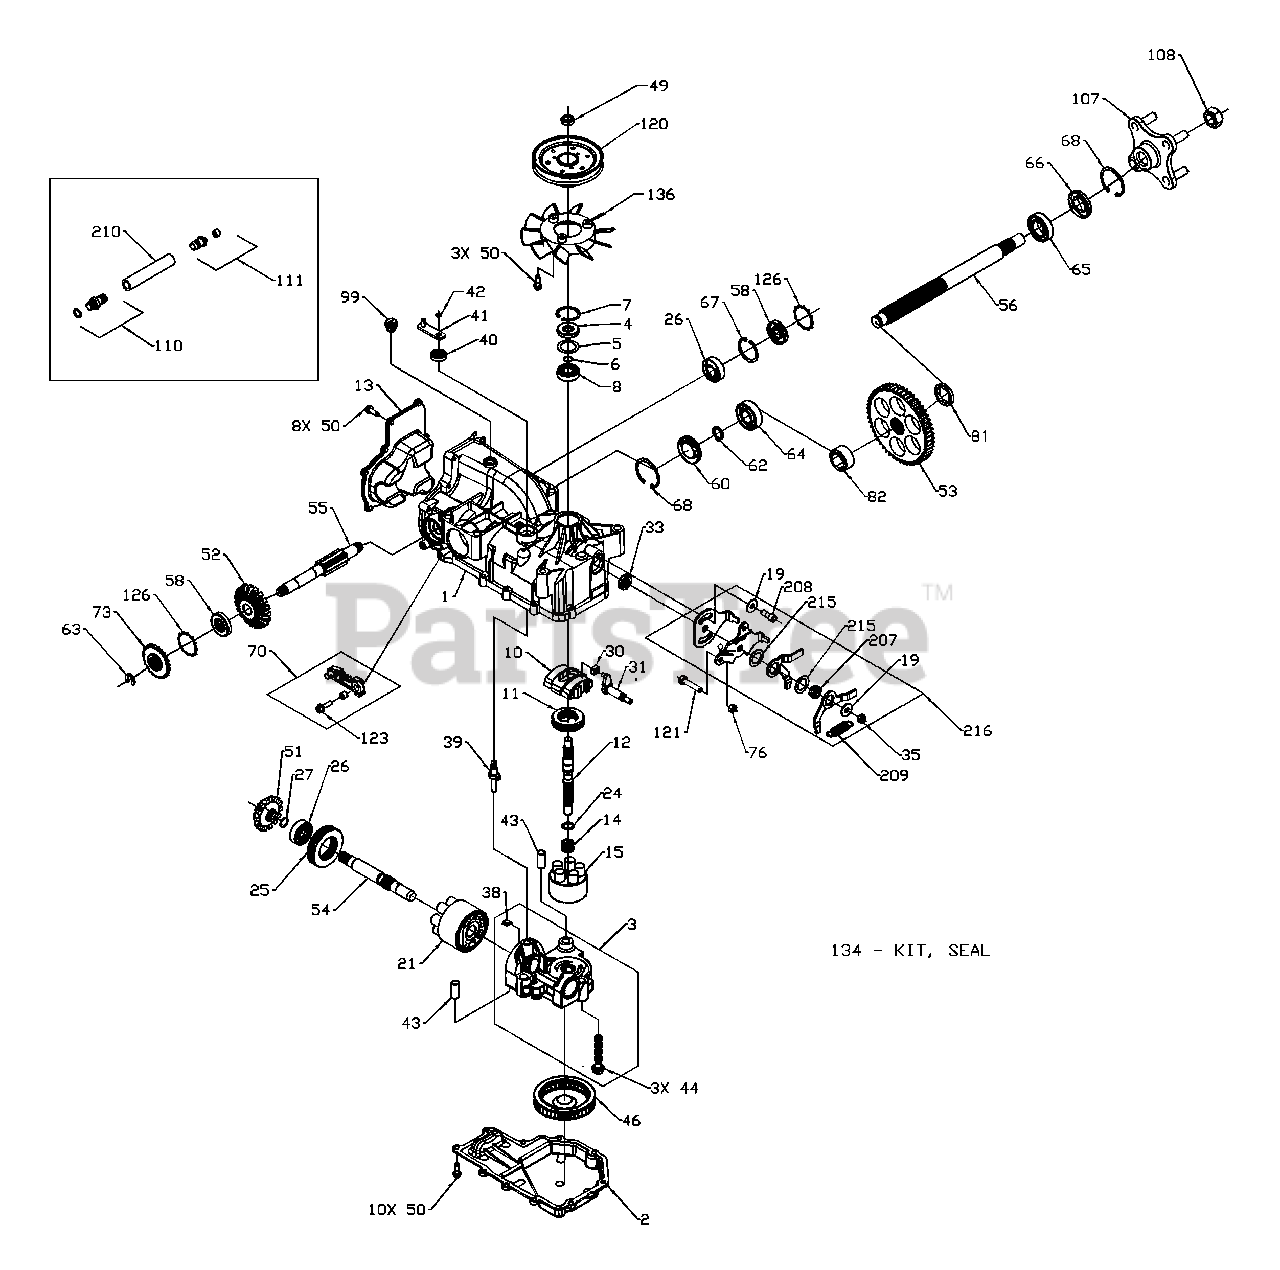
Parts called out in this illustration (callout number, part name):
1	KIT, HOUSING-MAIN
2	LOWER HOUSING
3	KIT, CENTER SECTION
4	SEAL, LIP 15 x 35 x 7
6	RING, WIRE RETAINING
7	RING, RETAINING
8	BALL BEARING
10	VARIABLE SWASHPLATE
11	THRUST BEARING 30 x 52 x 13
12	SHAFT, INPUT
13	COVER-BACK
14	SPRING, BLOCK
15	10cc CYLINDER BLOCK ASSY.
19	WASHER, .34 x .88 x .06
21	21cc CYLINDER BLOCK ASSY.
24	WASHER, BLOCK THRUST
25	THRUST BEARING 42 x 68 x 16
26	BALL BEARING
27	RING, WIRE RETAINING
31	TRUNNION ARM
33	SEAL, LIP 12 x 25 x 7
35	NUT, HEX LOCK LOCK 5/16-24 UNJF
38	KIT, BYPASS PLATE
39	BYPASS ACTUATOR
40	SEAL, LIP 10 x 25 x 7
41	ARM, BYPASS
42	RING, RETAINING
43	PIN, HOLLOW .39 x .5 x 1
44	BOLT, HEX FLANGE 3/8-24 x 2.5
49	HEX LOCK NUT 1/2-20 (NYLON INSERT)
50	SCREW, 1/4-20 x .75
51	14T BEVEL GEAR
52	19T BEVEL GEAR
53	53T SPUR GEAR
54	SHAFT, MOTOR
55	SHAFT, BRAKE
56	SHAFT, AXLE
58	SEAL, LIP 17 x 40 x 7
60	SEAL PLUG-SIDE
62	RING, RETAINING-AXLE
63	RING, RETAINING
64	BEARING-BALL 20 x 47 x 14 (6204)
65	BEARING-BALL 25 x 47 x 12 (6005)
66	SEAL, LIP 25 x 47 x 7
67	RING, RETAINING
68	RING, RETAINING-AXLE
70	ASSEMBLY, BRAKE ARM SERVICE
73	BRAKE DISC
76	NUT, HEX 5/16-18
81	AXLE BUSHING
82	AXLE BUSHING
99	PLUG, PLASTIC (Shipping)
107	HUB ASSEMBLY
108	NUT, HEX 3/4-16
110	FITTING O-RING ASSEMBLY
111	CAP VENT ASSEMBLY
120	PULLEY, 4.5 x 1.625
120	KIT, FAN/PULLEY
121	BOLT, 5/16-18 x 1.50
123	SCREW, HFHC 1/4-28 x 7/8 (PATCH)
126	RING, RETAINING
134	KIT, SEAL
136	FAN, 6" 10 BLADE
207	SPACER, RTN
208	SHCS 5/16-24 x .75 (PATCH)
209	SPRING, EXTENSION
210	HOSE .5 x 4
215	WASHER, PLASTIC 1.19 x .7
216	KIT, RTN SCISSOR
